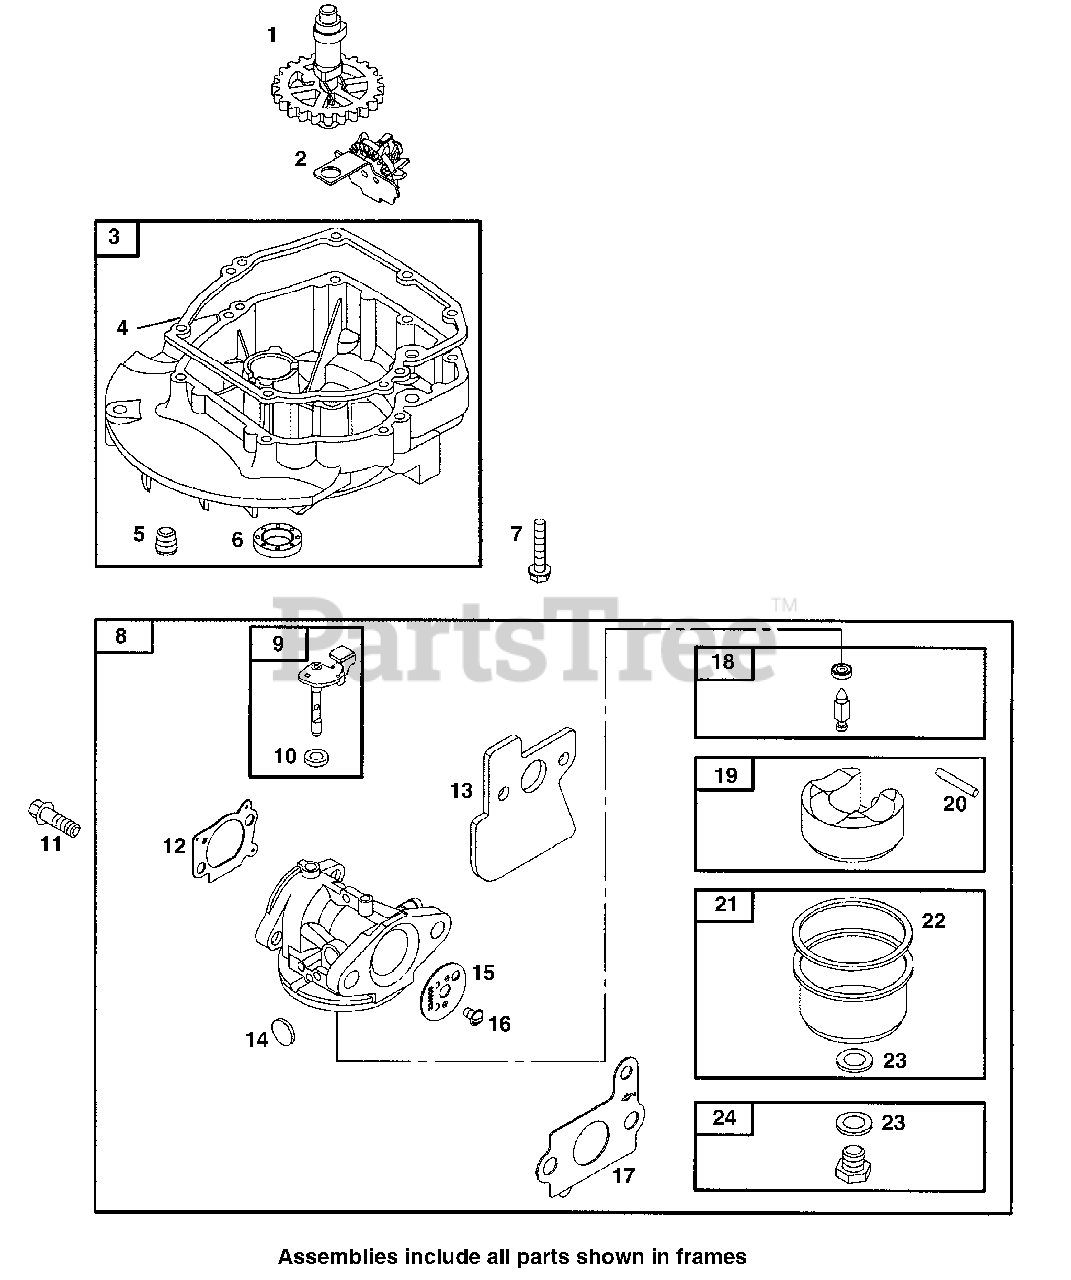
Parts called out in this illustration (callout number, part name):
2	Governor/Oil Slinger
3	Engine Sump
4	Crankcase Gasket
5	Oil Plug
6	Oil Seal
7	Hex Screw
8	Carburetor Assembly
9	Throttle Shaft
10	Throttle Shaft Seal
11	Hex Screw
12	Air Gasket Cleaner
13	Carburetor Spacer
14	Welch Plug
15	Throttle Valve
16	Round Head Screw
17	Intake Gasket
18	Needle Valve
19	Carburetor Float
20	Float Hinge Pin
21	Float Bowl
22	Float Bowl Gasket
23	Seal Washer
